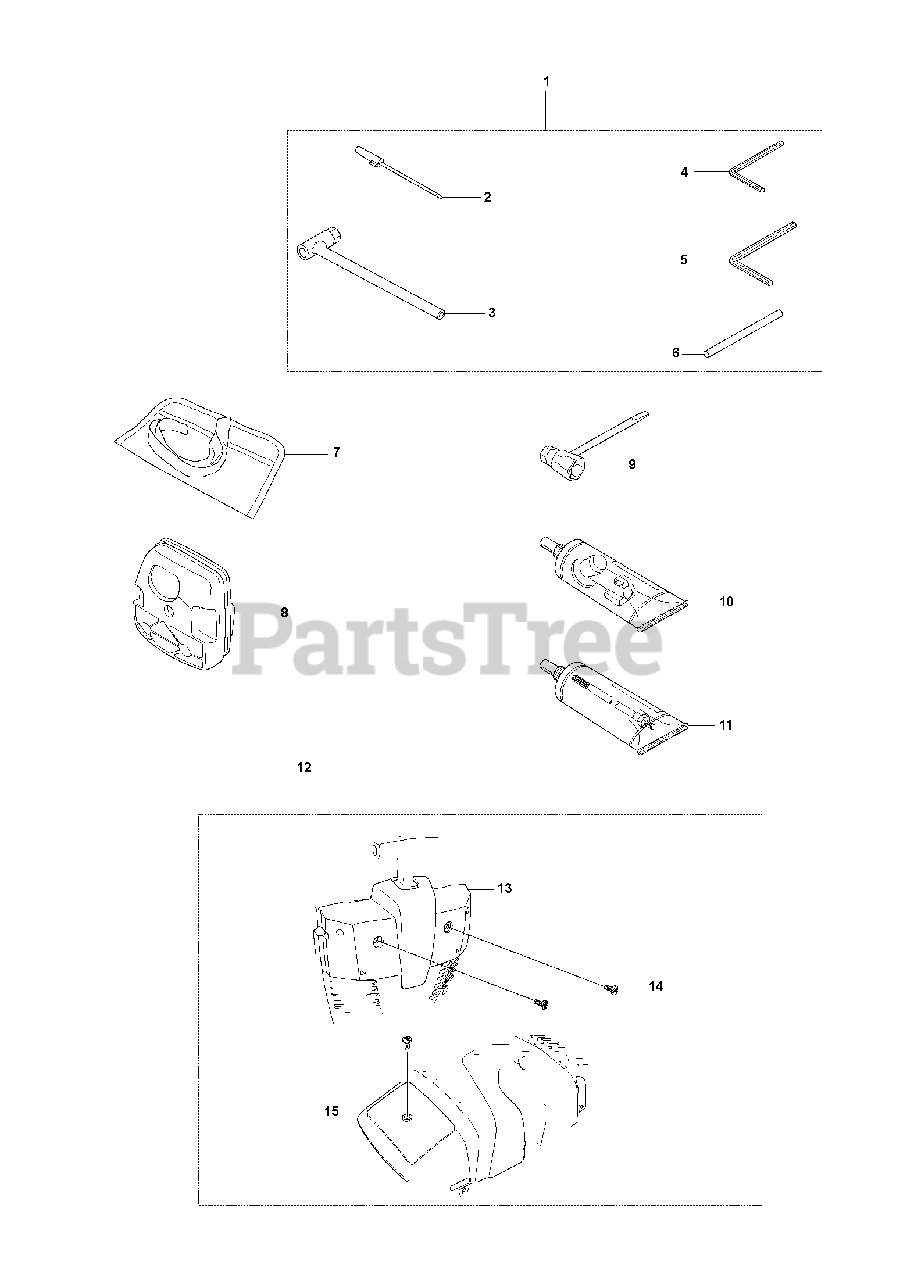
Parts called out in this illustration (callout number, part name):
1	TOOL KIT
2	SCREWDRIVER
3	SCRENCH
4	L-KEY WRENCH
5	L-SPANNER
6	LOCKING PIN
8	AIR FILTER
9	COMBI TOOL
12	WINTER SET
13	COVER
14	SCREW
15	COVER
